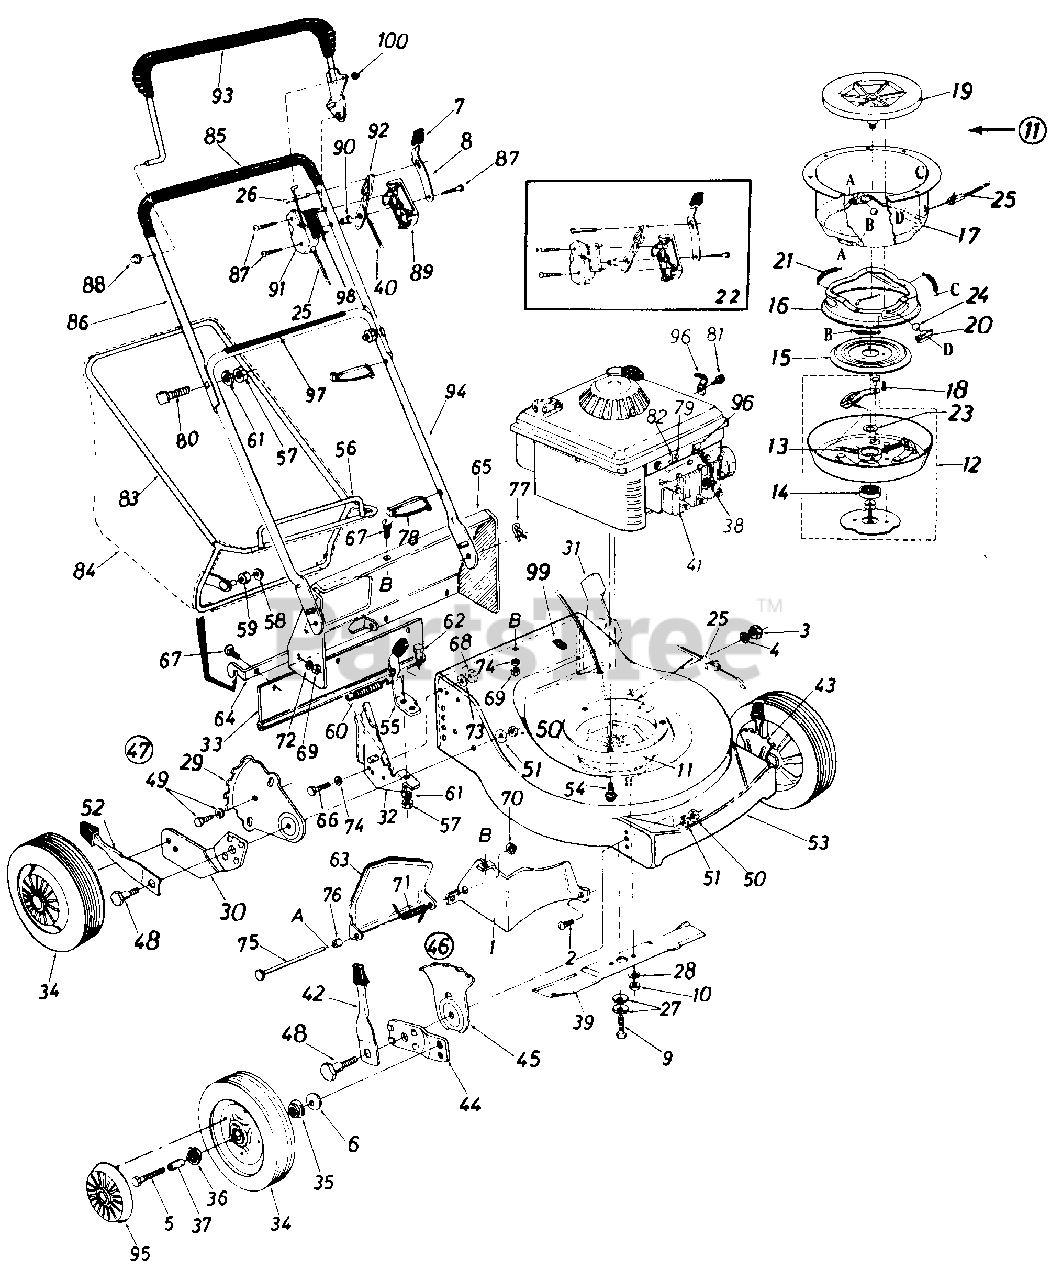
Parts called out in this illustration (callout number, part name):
1	Rear Baffle
2	Carriage Bolt 1/4-20 x .50" Lg.*
3	Hex Nut 1/4-20 Thd.*
4	L-Wash. 1/4" I.D.*
5	Axle Bolt
6	Bell-Wash. .400" I.D. x .88"
7	Spring Lever Knob
8	Lockout Spring
9	Hex Bolt 3/8-24 x 2.0" Lg. (Grade 8)
10	Hex Nut 3/8-24 Thd. (Grade 8)
11	Blade Brake/Clutch Ass'y. Comp.
12	Clutch Blade Housing Ass'y.
13	Compression Spring
14	Ball Brg. .669" I.D. x 1.574" O.D.
15	Clutching Cone
16	Brake Cup Cone
17	Clutch Housing
18	Hex Tap L-Scr. 1/4-20 x .75"
19	Fan Adapter
20	Ball Block
21	Extension Spring
22	Control Housing Comp.
23	Fl-Wash. .69" I.D. x 1.06"
24	Steel Ball .500" Dia.
25	Clutch Cable-46"
26	Lock Pin .314" Dia. x 1.7" Lg.
27	Bell-Wash. .400" I.D. x .88"
28	L-Wash. 3/8" I.D.*
29	Rear Index Plate
30	Rear Pivot Bar-R.H.
31	Handle Brkt. Ass'y.-L.H.
32	Handle Brkt. Ass'y.-R.H.
33	Rear Flap Ass'y.
35	Bearing
36	Bearing
37	Spacer
38	Spark Plug Insulator
39	21" Blade
40	Throttle Wire-58" (Black)
41	Engine
42	Spring Lever w/Knob
43	Front Height Adj. Ass'y.-L.H.
44	Front Pivot Bar
45	Front Index Plate
46	Front Height Adj. Ass'y.-R.H.
47	Rear Height Adj. Ass'y.-R.H.
48	Shld. Bolt .500" Dia. x .375
49	Hex Self-Tap Scr. 1/4 x .62"
50	Hex Nut 3/8-16 Thd.*
51	Bell-Wash. .39" I.D. x 1.38"
52	Spring Lever w/Knob
55	Grass Catcher Lock Lever
58	Push Nut 3/8" Rod
59	Plastic Roller
60	Tension Spring
61	L-Wash. 5/16" I.D.
62	Shld. Bolt .437" Dia. x .162" 4.
63	Chute Door
64	Grass Catcher Hitch Brkt.
65	Rear Discharge Deck Section
66	Hex Bolt 1/4-28 x .75" Lg.
67	Carr. Bolt 1/4-20 x .75" Lg.
68	Hex Nut 1/4-28 Thd.
69	Sems Nut 1/4-20 Thd.
70	Push Nut 1/4" Rod
71	Torsion Spring
72	Fl-Wash. .285" I.D. x 1.25"
73	Bell-Wash. 1/4" I.D. x .88" O.D.
74	L-Wash. 1/4" I.D.
75	Hinge Pin .250" Dia. x 7.88"
76	Spacer .262" I.D. x .31" O.D.
77	Intern. Cot. Pin 5/16" Dia.
78	Cable Tie
79	Hex B-Tap Scr. #10 x .62"
80	Curved Hd. Bolt 5/16-18 x 1.38"
81	Hex B-Tap Scr. #10 x .38" Lg.
82	Casing Clamp
83	Grass Catcher Upper Frame
84	Grass Bag (Without Flip Top)
86	Upper Handle (Chrome)
87	Truss Mach. Hl-B Tap Scr. #12 x 1.50" Lg.
88	Cap Speed Nut 5/16" Rod
89	Control Panel Half
90	Control Disc Pin
91	Clutch Panel Half
92	Throttle Control Lever
93	Control Handle-L.H.
94	Lower Handle (Chrome)
95	Hub Cap
96	Casing Clamp
97	Instruction Label-Handle
98	Control Label-Throttle
99	Plastic Plug
100	Push Cap
